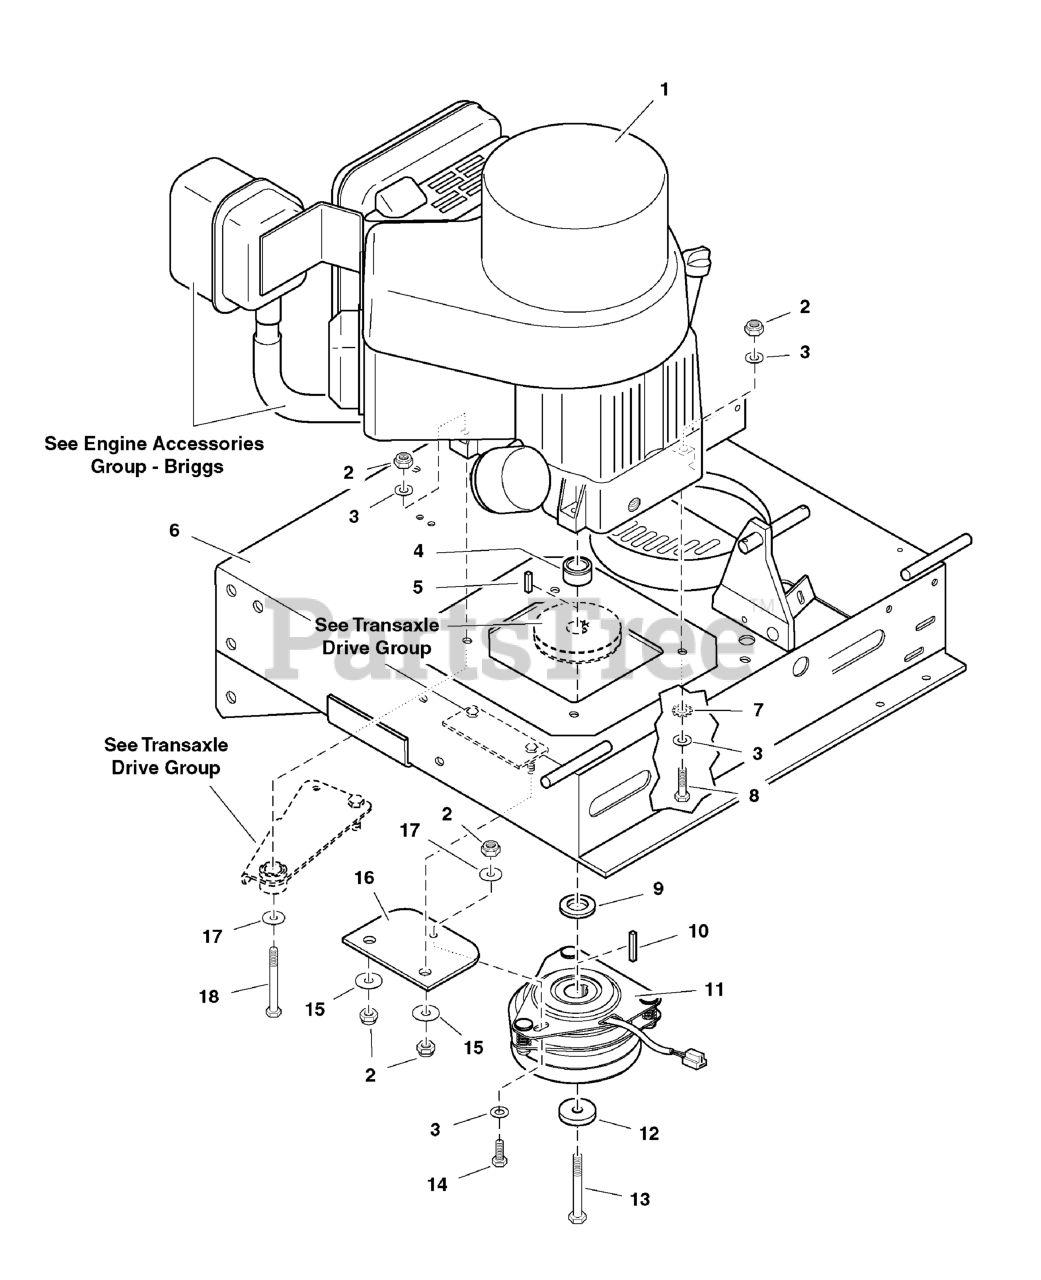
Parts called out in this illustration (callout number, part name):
2	NUT, 5/16-18 Hex Nylon Lock
3	WASHER, 5/16" SAE
4	CRANKSHAFT SPACER
5	KEY, 1/4" SQ. X 1-1/4
6	ENGINE DECK
7	WASHER, 5/16" Internal Tooth Lock
8	BOLT, 5/16-18 x 1-3/4
9	SPACER, 1.00 X 1.75 X .38
10	KEY, 1/4 SQ. X 1
11	CLUTCH, Electric, 1" Shaft
12	SPACER, .45 x 1.62 x .37
13	CRANKSHAFT BOLT, 7/16 x 3
14	BOLT, 5/16-18 X 3/4 GD5
15	WASHER, Clutch Anchor
16	CLUTCH ANCHOR PAD
17	WASHER, 5/16" Fender
18	BOLT, 5/16-18 x 3
